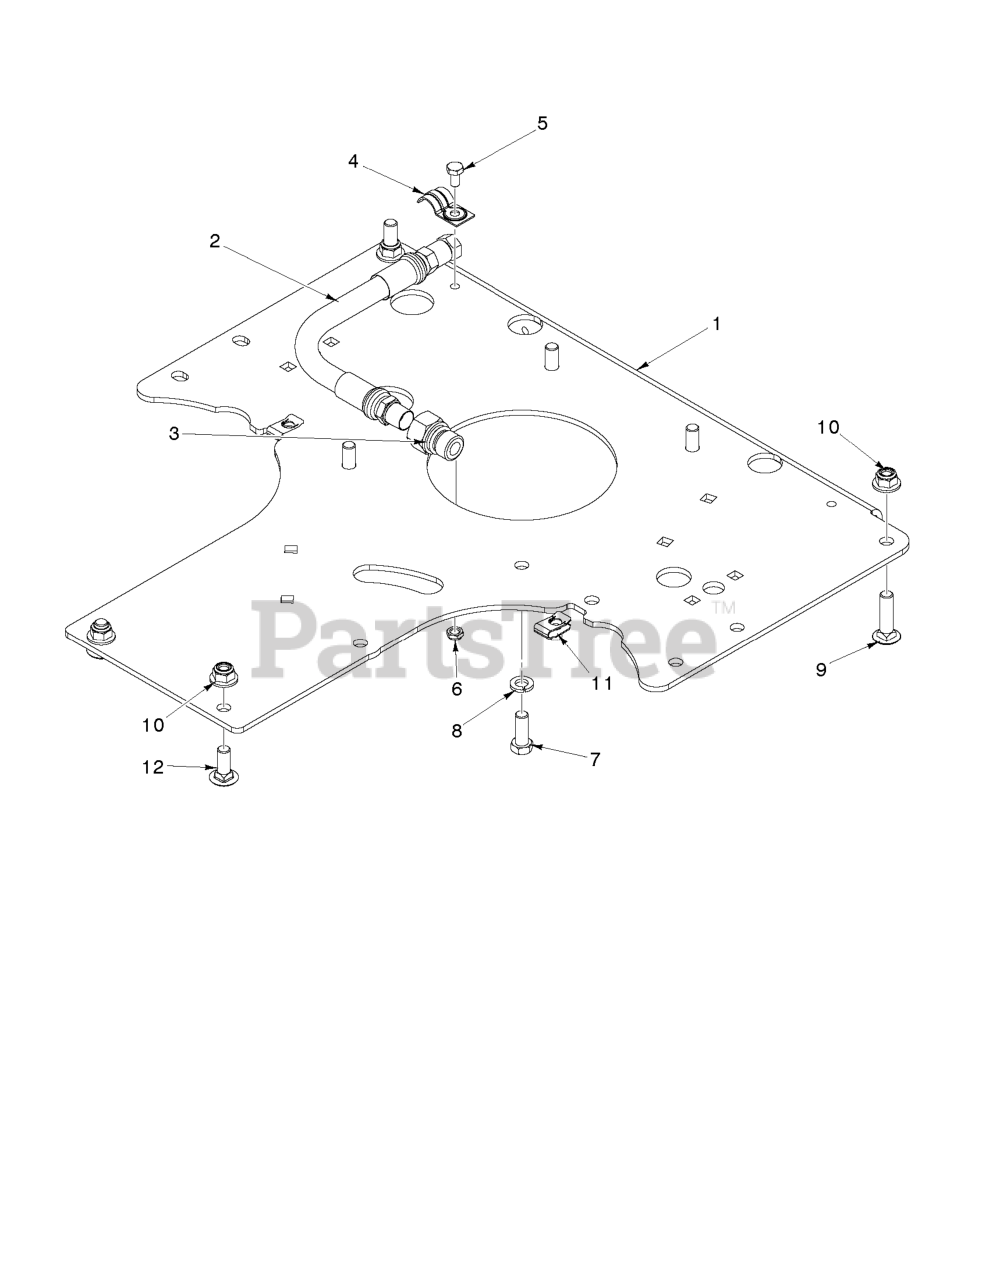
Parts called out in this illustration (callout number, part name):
1	Engines
2	HOSE.ASSEMBLY.OIL.DRAIN
3	ADAPTER, OIL DRAIN
6	Hardware
9	GSPW Bolts
11	U-CLIP 5/16-18 NUT RETAINER
